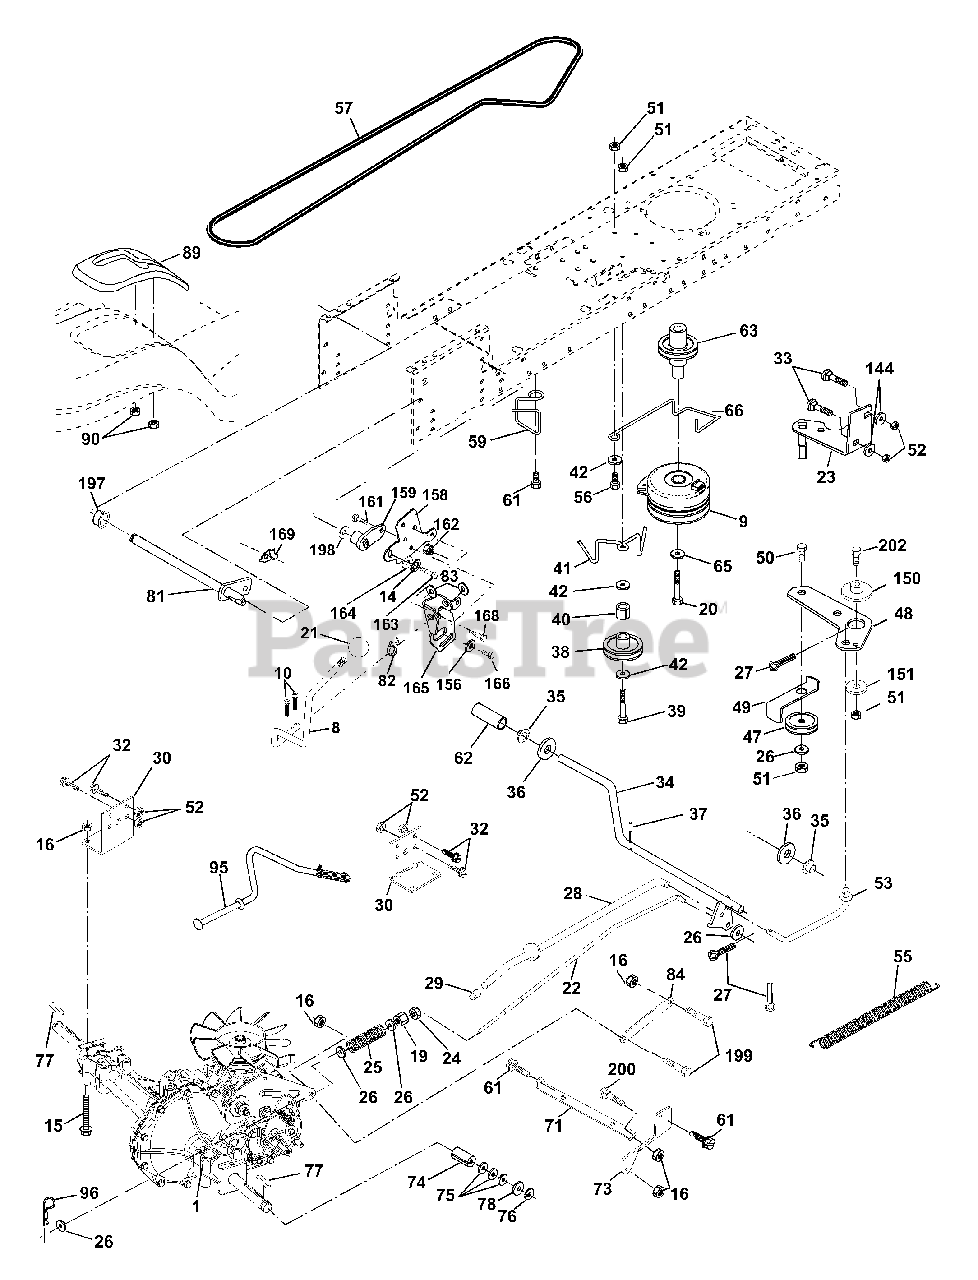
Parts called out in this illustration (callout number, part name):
8	Rod Shift Fender Adjust STLT
9	Clutch Electric
10	Pin Cotter 1/8 x 1 CAD
14	Washer Lock Hvy Helical
15	Bolt Hex 5/16-18 Unc Flghd
16	Nut Lock Hex W/Ins. 5/16-18 Unc P
19	Nut Lock Hex W/Ins 3/8-16 Unc
20	Bolt, Hex 7/16-20 x 4-1/4 Ga. 5
21	Knob Deluxe 1/2-13 UNC BLK/BLK
22	Rod, Brake Hydro
23	Bracket Asm Mtg CL
24	Nut Hex Jam 3/8-16 UNC
25	Spring, Brake Rod
26	Washer
27	Pin Cotter 1/8 x 3/4 CAD.
28	Rod, Parking Brake
29	Cap, Parking Brake
30	Bracket, Transaxle
32	Bolt Hex Hd 5/16-18 Unc x 3/4
33	Bolt Carriage 5/16-18 UNC x 3/4
34	Shaft, Foot Pedal
35	Bearing, Nylon
37	Pin, Roll
38	Pulley, Idler, Flat
40	Spacer Split
41	Keeper, Belt Idler
42	Washer 13/32 x 13/16 x 12 Ga
47	Pulley, Idler, V-Groove Plastic
48	Bellcrank Clutch Grnd Drv STL
49	Retainer, Belt Style Spring
52	Nut Crown Lock 5/16-18
53	Link, Clutch
55	Spring, Return, Clutch
56	Bolt, Fin Hex 3/8-16 UNC x 1 1/4
57	V-Belt, Ground Drive
59	Keeper, Center Span
61	Screw 3/8-16 x 3/4
62	Cover, Pedal
63	Pulley, Engine
65	Washer Lock Hvy HLCL Spr 7/16
66	Keeper Belt Engine
71	Strap Torque Lh Hydro
73	Strap Torque Rh Hydro
74	Spacer, Axle
75	Washer 25/32 x 1-1/4 x 16 Ga.
77	Key, Square
78	Washer 25/32 x 1-5/8 x 16 Ga
81	Shaft Asm Cross Tapered
82	Spring Torsion T/A
83	Washer 17/32 x 3/4 x 16 Ga.
84	Link Transaxle
89	Console, Shift Hydro STLT
90	Nut Self-Thd Wsh-Hd 1/4 Zinc
95	Control Asm. Bypass Hydro
96	Retainer Spring 1" Zinc/Cad
144	Washer 11/32 x 5/8 x 16 Ga.
150	Bushing Bellcrank Grd Drive
151	Washer 13/32 x 2 x 10 Ga.
156	Washer Srrted 5/16ID x 1.125
158	Bracket Shift Mount
159	Hub Tapered Flange Shift Lt
161	Bolt Rdhd Sqnk 1/4-20 x 3/4 Gr 5
162	Nut Crownlock 1/4-20 Unc
163	Bolt Hex Fin 1/4-20 Unc x 1 Gr 5
164	Washer 5/8 x .281 x 10 Ga
165	Bracket Pivot Lever
166	Screw 5/16-18 x 5/8
168	Bolt Shoulder 5/16-18 x .561
169	Plate Fastening STLT/CRD
197	Nyliner Snap 5/8" ID
198	Washer Nyl 7/8 ID x .105 Hyd
199	Bolt Shoulder 5/16-18 Unc
200	Bolt Rdhd Sq Neck Unc
201	Screw Thdrol 3/8-16 x 3/4
